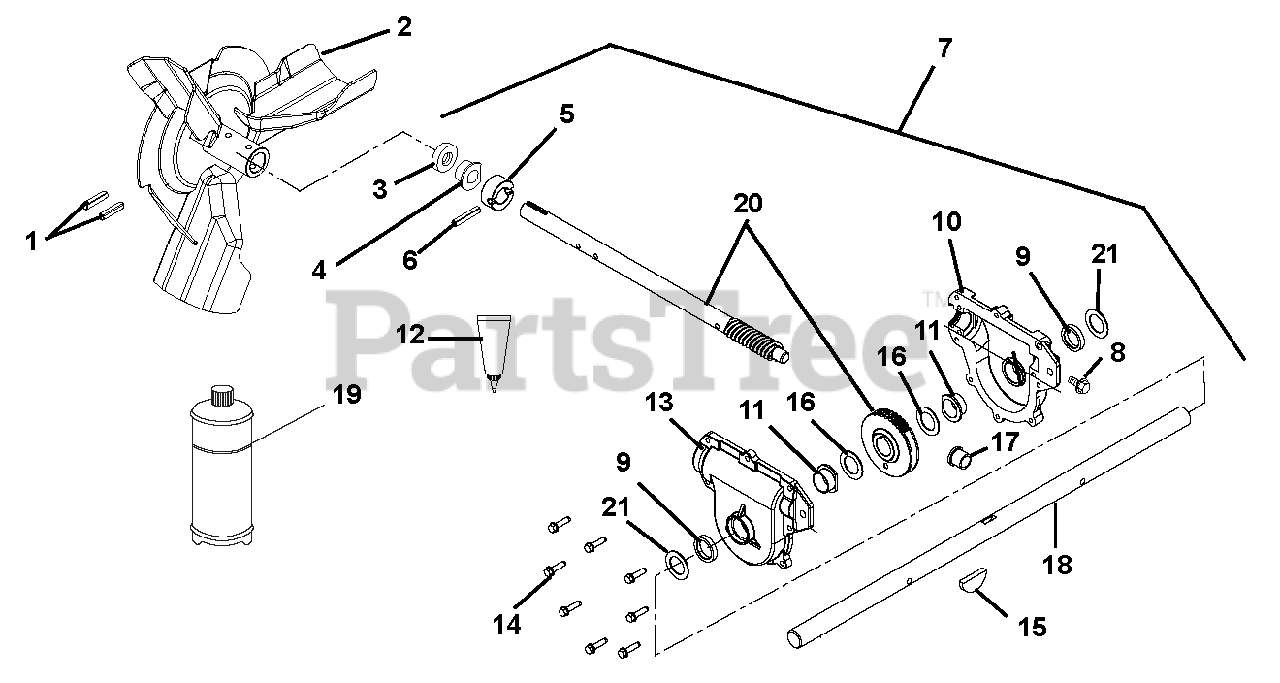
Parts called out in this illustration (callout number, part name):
1	PIN-ROLL .250X1.75
2	IMPELLER, 3 BLADE-14"
3	SEAL-OIL .875X1.375X.25 RBR OD
4	BSHG-FLG .876 X 1.500 X .750
5	THRUST COLLAR, .875" ID
6	PIN-GRV .250X1.50 TP E
7	GEAR CASE, ALUM-LARGE 32"
8	SCR-TAP .38-16X.75 ROLOK YZ WX
9	SEAL-OIL 1.000X1.375X.250
10	GEARCASE, ALUMINUM, LH
11	BSHG-FLG 1.003X1.5X.625
12	LOCTITE 518 GASKET--6ML TUBE
13	GEARCASE, ALUMINUM, RH
14	@SCR-TAP .25-20X1.00 HWH TR YZ
15	KEY-WDRF .25X.875X.375 SAE A
16	WSHR-HRD-THRS 1.007X1.542X.062
17	BSHG-FLG .629 X 1.000 X .750
18	SHAFT, RAKE-32"
19	ARIENS 16 OZ.BOTTLE OF L2 LUBE
20	ASSY, WORM SHAFT & GEAR
21	WSHR-FL-STL 1.010X1.505X.062YZ
